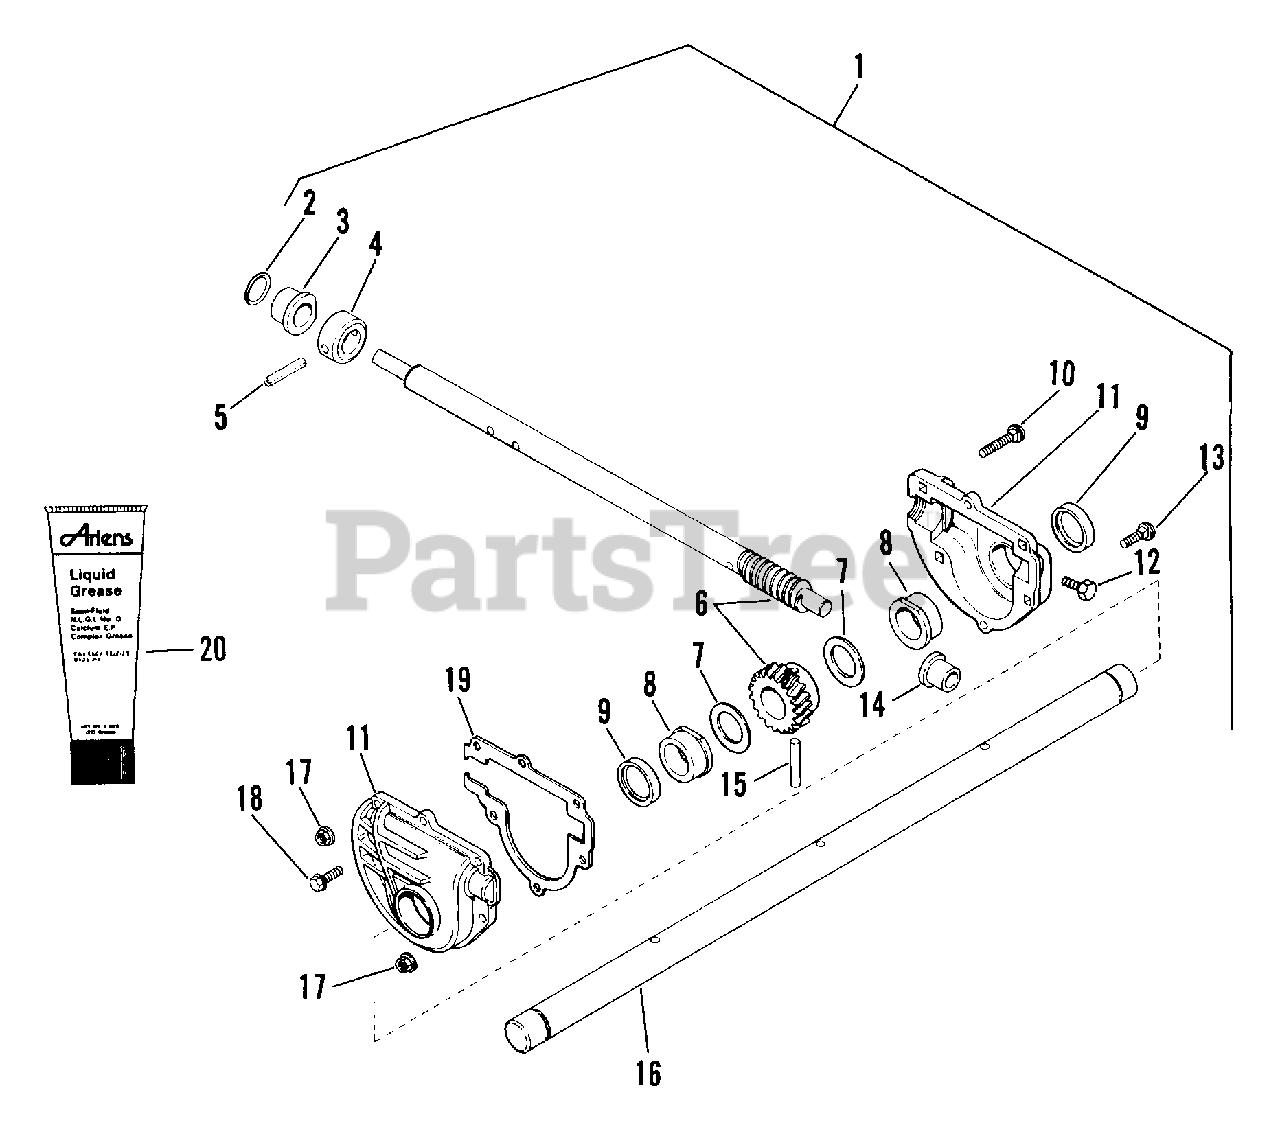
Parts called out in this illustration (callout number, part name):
1	GEAR CASE ASSEMBLY
2	O-RING .250X.943X.103
2	SEAL .750X1.00X.156
3	BSHG-FLG .750X1.000X.750X1.250
4	THRUST COLLAR
5	PIN-GRV .188X1.25 TP A
6	WORM SHAFT & GEAR ASSY
7	WSHR-HRD-THRS 1.007X1.542X.062
8	BSHG-FLG1.000X1.12X.62X1.50BR
9	SEAL 1.000X1.312X.150
10	BLT-RDHDSQNK .25-20X1.25 GR5PL
11	GEAR CASE HALF L H
11	L. H. GEAR CASE HALF
11	GEAR CASE HALF R H
11	R. H. GEAR CASE HALF
12	SCR-TAP .375-16X .50 HWH PL TR
13	BLT-RDHDSQNK .25-20X.88 PL
14	BSHG-FLG .500X.750X.750X1.000
15	PIN-GRV .313X1.44 TP C
16	AUGER SHAFT
17	NUT-LK-FLG .250-20 PL
18	SCR-TAP 10-24X.75 HWH PL TR
19	GASKET
20	8 OZ TUBE OF LIQUID GREASE
